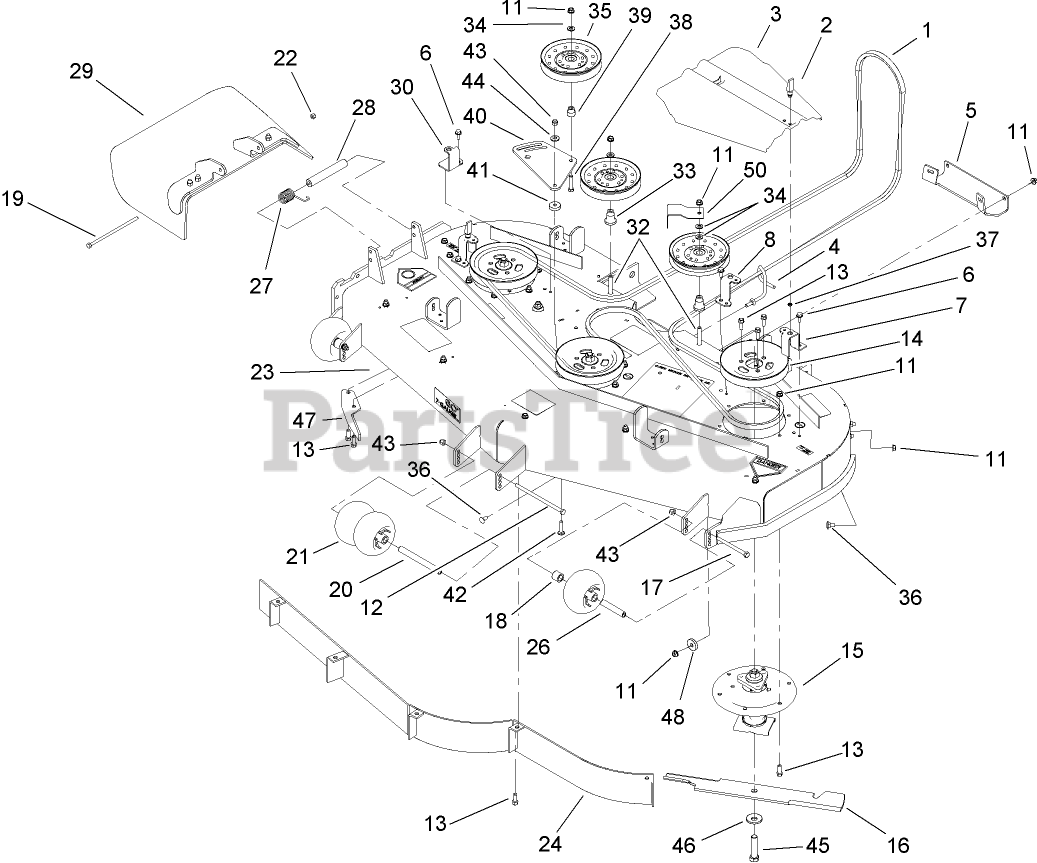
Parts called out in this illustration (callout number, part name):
2	LATCH-SWELL
3	COVER-BELT
4	GUIDE-BELT
5	Plate-Skid
6	SCREW-HWHTF
7	BRACKET-COVER
8	BRACKET-COVER, TALL
11	NUT-HHF, WHIZ
12	SCREW-HH
13	SCREW-HWH
14	Pulley
15	SPINDLE ASM
16	BLADE-HI FLOW
17	SCREW-HH
18	TUBE-SPACER
19	SCREW-HH
20	SPACER-WHEEL
21	ROLLER-SCALP, ANTI
22	NUT-LOCK, NI
23	DECK DECAL ASM
24	BAFFLE ASM
26	TUBE-SPANNER
27	SPRING-TORSION
28	SPACER
29	RUBBER DEFLECTOR ASM
30	BRACKET-COVER
32	SCREW-HH
33	MOUNT-PULLEY
34	WASHER-FLAT
35	Idler-Flat
36	SCREW-CARR
37	WASHER
38	SCREW-HH
39	BUSHING-IDLER
40	Plate-Idler
41	Spacer
42	SCREW-CARR
43	NUT-LOCK, NI
44	WASHER-BELLEVILLE
45	Screw-Cap
46	Washer-Blade Bolt, Heavy
47	BAFFLE-DISCHARGE
48	WASHER
50	GUIDE-BELT
